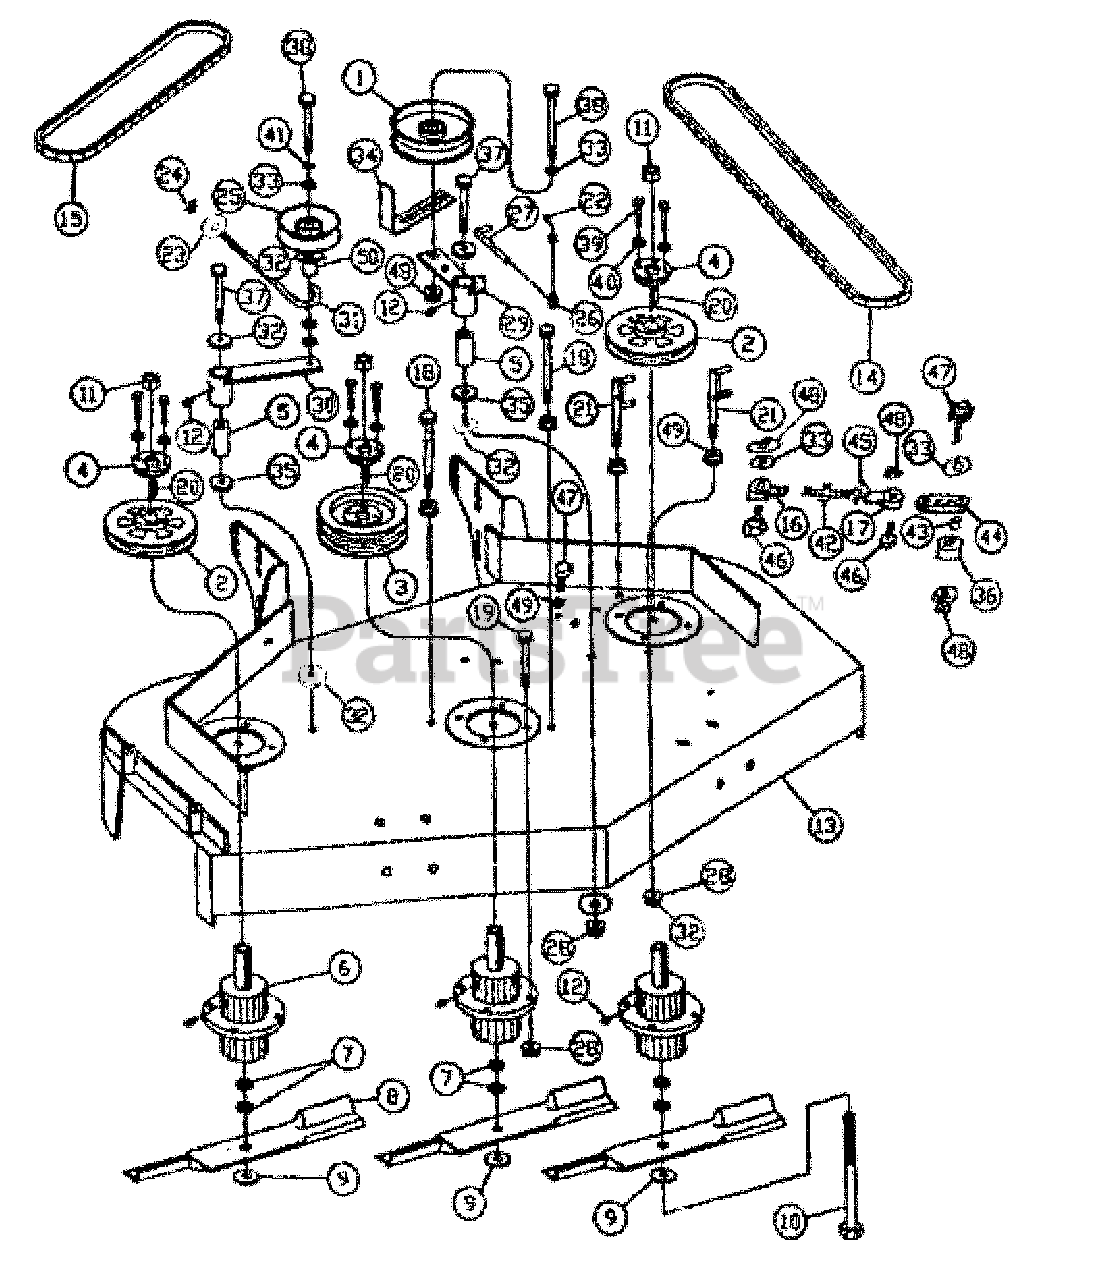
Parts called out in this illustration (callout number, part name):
1	100-013 IDLER PULLEY
2	100-025 PULLEY SINGLE
3	148-004 PULLEY DBL
4	100-026 H-BUSHING
5	100-024 PIVOT HUB
6	100-021 CUTTING HOUSE AS
7	100-022 SPACER 6
8	BLD 48` - WALKABOUT
9	100-023 WASHER
10	200-023 BOLT M16`1.5`245
11	200-017 NEX NUT M16`1.5
12	GREASE FTG (10 PACK) 200-026
13	148-002 BLUE DECK 48
14	148-006 BELT 48`
15	148-007 BELT BLD TO BLD
17	100-027 ROD END RH
18	200-028 NUT FLANGE M8
19	200-018 HEX BOLT M10-35
20	100-014 KEY 6.35`6`50
22	200-014 COTTER PIN 2`20
23	200-028 NUT FLANGE M8
25	148-008 IDLER PULLEY
26	100-018 SWIVEL
28	200-006 NYLON NUT M10
29	100-020 IDLER ARM WLDT.
30	148-009 DECK IDLER ARM
31	148-009 ROD BELT TENSION
32	100-019 WASHER
33	WASHER, 3/8 STD FLAT
34	100-033 BELT GUIDE
35	100-015 WASHER 2`26ID
36	100-031 SPACER 12
37	M10X1.5X70 HHB GR8.8
38	200-022 HEX BOLT M10`65
39	M8X1.25X30MM HHB
40	5/16HELICAL L-WASHER
41	3/8HELICAL L-WASHER
42	100-030 TURN BUCKLE ROD
43	100-032 LINK BUSHING
44	100-029 LINK IDLER ARM
46	200-018 HEX BOLT M10-35
47	200-019 HEX BOLT M10-40
48	200-006 NYLON NUT M10
49	200-016 NUT FLANGE M10
50	148-011 SPACER 16
